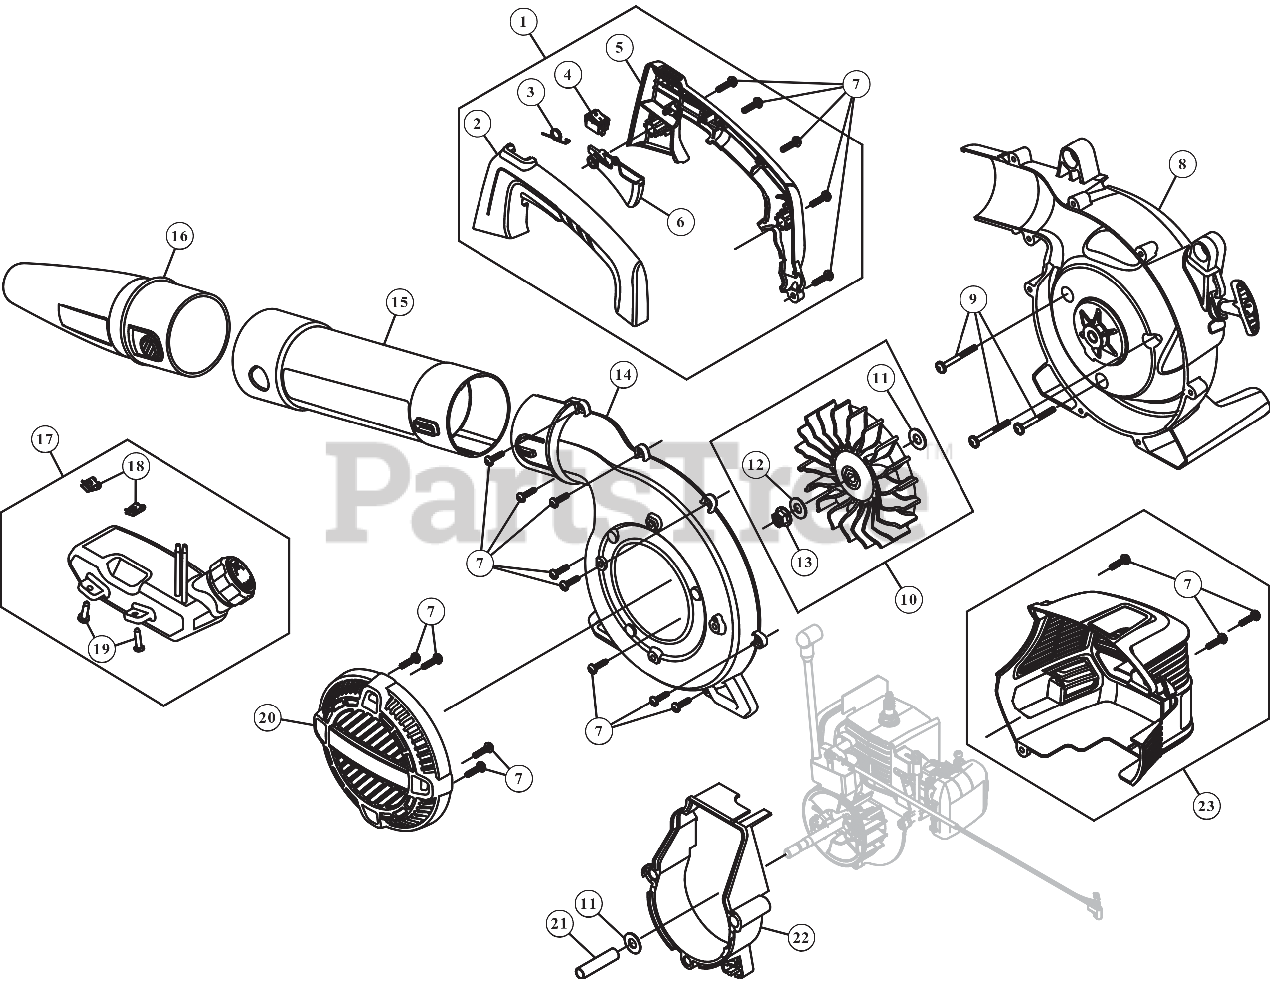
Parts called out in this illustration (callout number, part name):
1	HANDLE ASSEMBLY
2	HANDLE (LH)
3	SPRING TRIG
4	SW, MOMENTARY ON/O
5	HANDLE ASSEMBLY (RH)
6	THROTTLE TRIGGER
7	SCREW 8-16 x 3/4
8	IMPELLER HSG ASSEMBLY (RH)
9	SCREW 10/32
10	IMPELLER ASSEMBLY
11	FLAT WASHER
12	LOCK WASHER
13	NUT 3/8-24
14	IMPELLER HSG ASSEMBLY (LH)
15	TUBE UPPER
16	NOZZLE
17	FUEL TANK ASSEMBLY
18	NUT, TINNERMAN U-T
19	SCREW:10-6 x .75
20	INTAKE COVER
21	SPACER
22	ENGINE ADAPTER
23	ENGINE COVER
